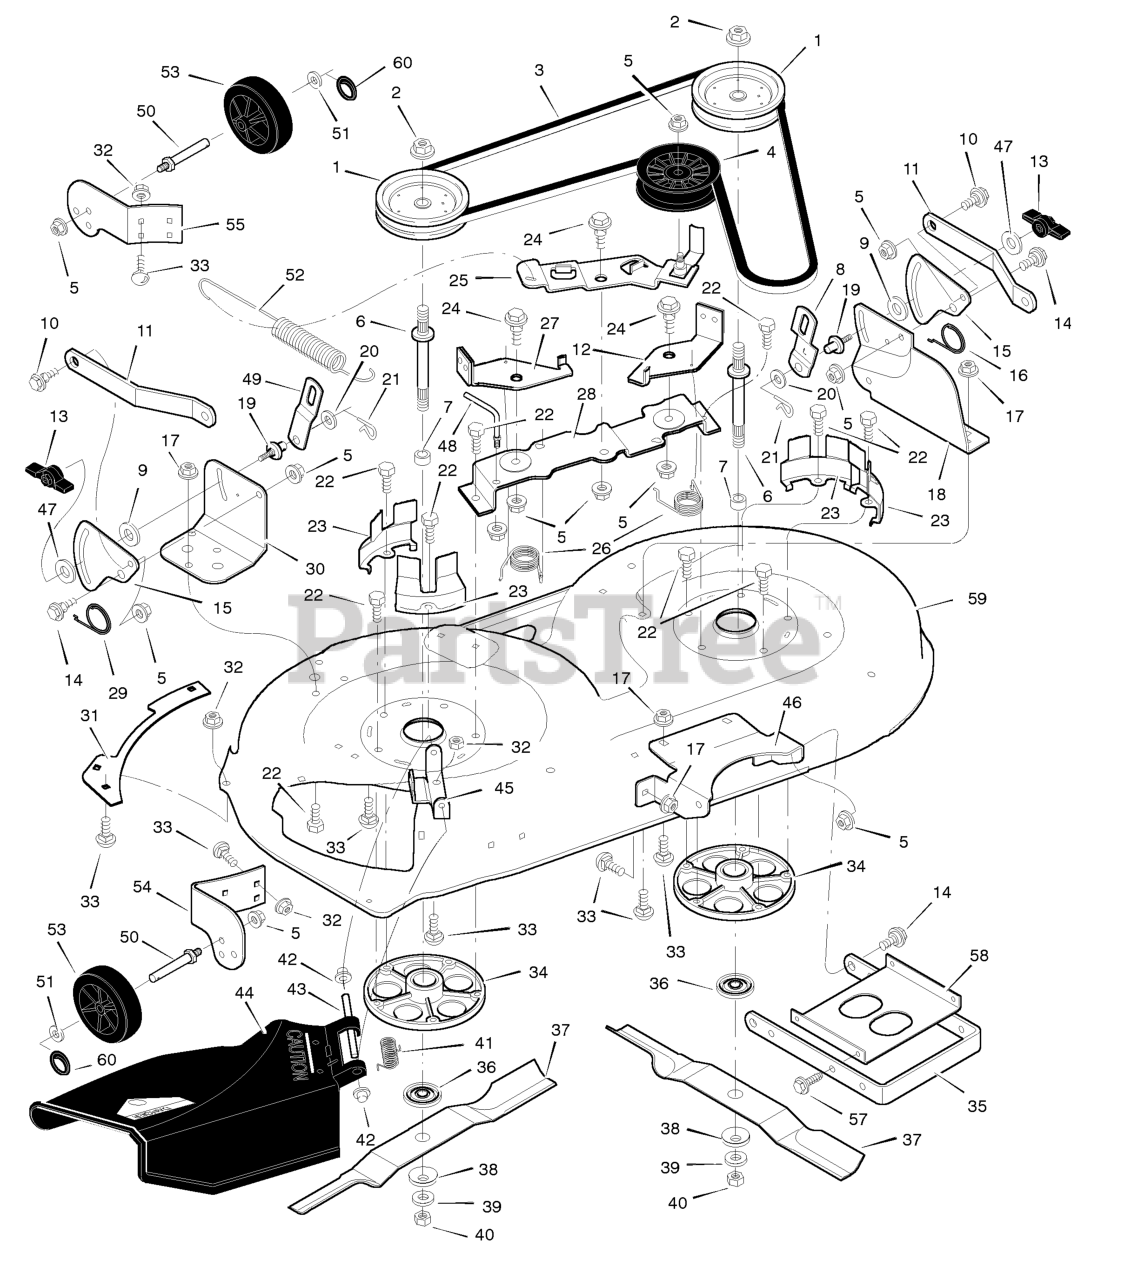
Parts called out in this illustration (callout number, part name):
1	Pulley, Jackshaft
2	Nut, Hex
3	Belt, Mower Drive
4	Pulley, Idler
5	Nut, Flange
6	Jackshaft
8	Link, Left Lift
9	Pad, Friction
10	Bolt, Shoulder
11	Bracket, Suspension
12	Pad Assembly, Left Brake
13	Knob
14	Bolt, Shoulder
15	Plate, Suspension
17	Nut, Flange
18	Bracket, Suspension
19	Pin, Hanger
21	Pin, Hair
22	Bolt
23	Cover, Pulley
24	Bolt, Shoulder
25	Arm, Idler
27	Pad Assembly, Right Brake
28	Bracket, Brake
30	Bracket, Suspension
32	Nut, Flange
33	Bolt, Carriage
34	Mandrell Housing
35	Bracket, Suspension
36	Adapter, Blade
42	Cap, Push On
43	ROD, Deflector
44	Deflector Assembly
45	Bracket, Deflector Hinge
46	Bracket, Front Hanger
48	Guide, Belt
49	Link, Right Lift
50	BOLT, Gauge Wheel
52	Spring, Extension
53	Wheel, Gage
54	Bracket, Right Wheel
55	Bracket, Left Wheel
58	Stiffener
59	Housing, Blade, Complete (NO LONGER AVAILABLE)
59	Housing, Blade (Housing Only)
60	Ring, Locking
